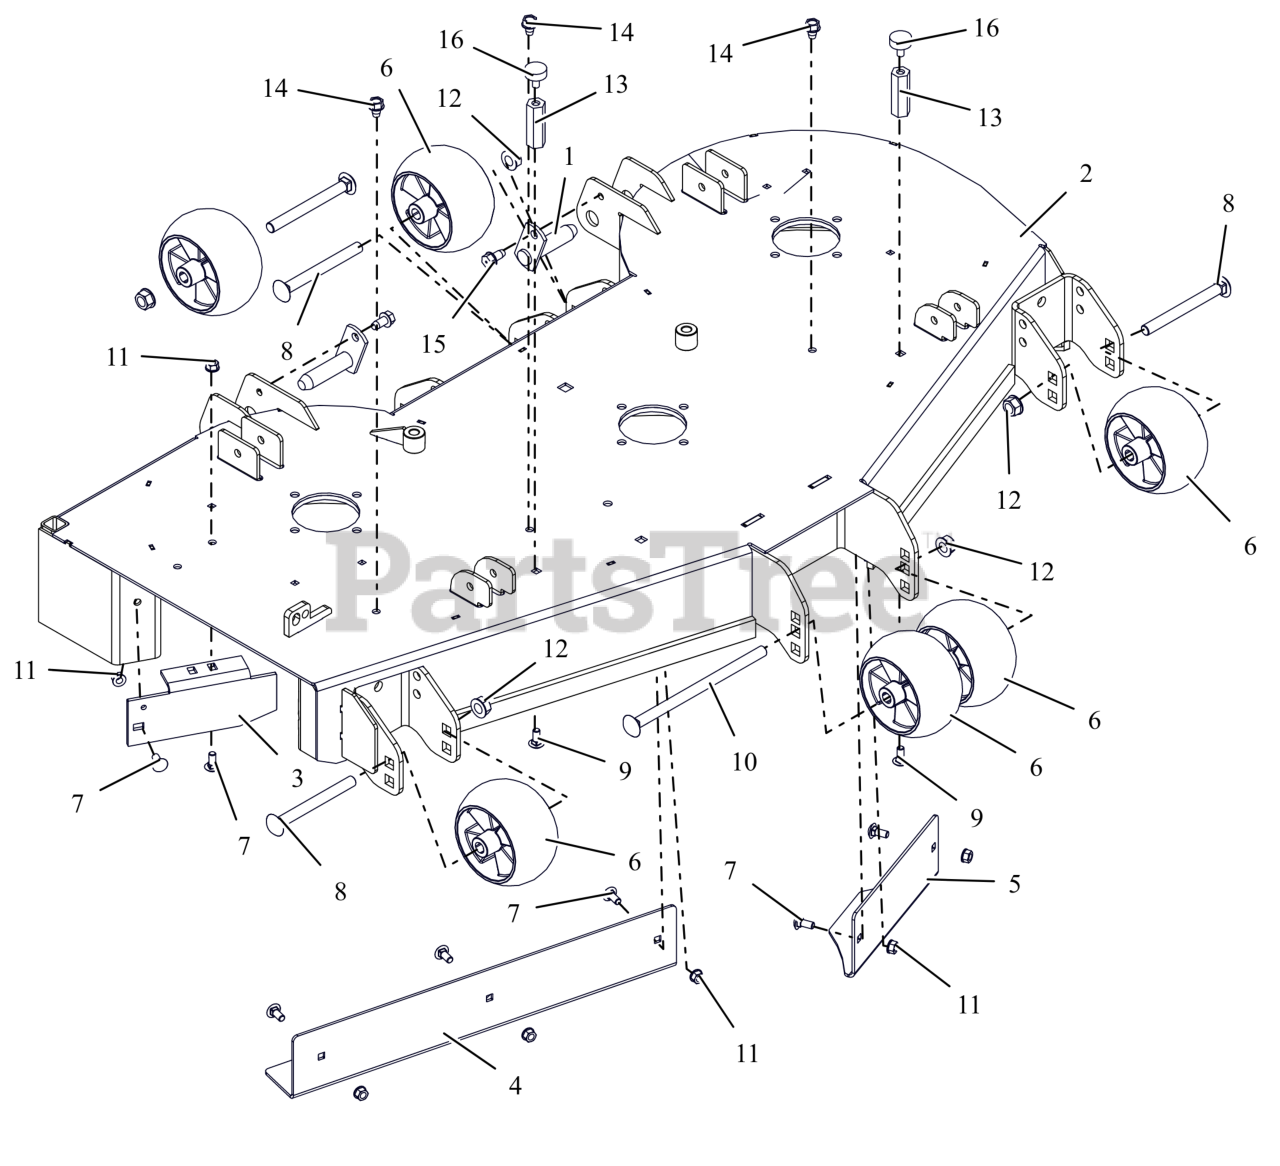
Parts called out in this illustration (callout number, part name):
1	WLDMT, MOWER MTG. PIN (BLACK)
2	KIT, 48" PRO-WALK DECK W/ DECALS (RED)
3	44"-48" SIDE DISCH BAFFLE -RED
4	BAFFLE, 48" RH VACUUM (RED)
5	BAFFLE, 44/48" LH VACUUM (RED)
6	WHEEL, ANTI SCALP - 5X3 CTR W/RIBS
7	BLT,RHSN .31-18X.75 G5 ZCC
8	BLT, RHSN .50-13X5.00 G5 ZCC
9	BTL,RHSN .313-18 X 0.75 G5 ZCC LT
10	BTL,RHSN .500-13 X 8.5S G5 ZCC
11	NUT,LK-CTR-FLG .31-18 GF ZCC
12	NUT-LK-CTR-FLG .500-13 GG ZCC
13	NUT, .31-18X2.25 LG COUPLING
14	SCR,TAP .375-16X.50 HWH TR ZCC
15	SCR,TAP .375-16X.75 HWH TR ZCC
16	BUMPER, RUBBER
